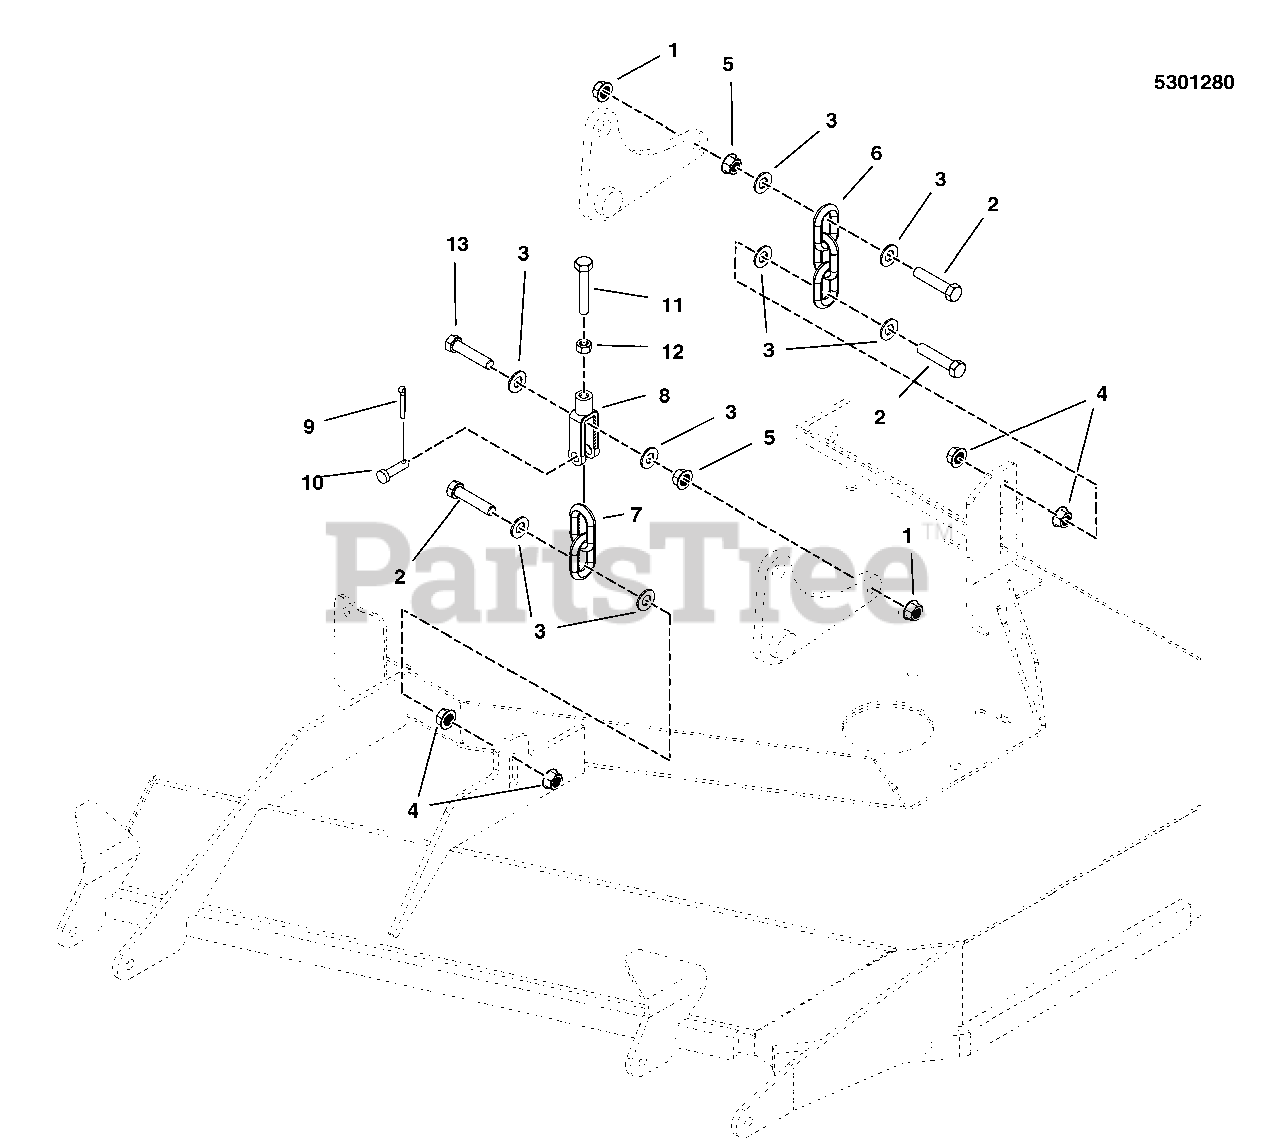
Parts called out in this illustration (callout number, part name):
1	NUT, 3/8-16 HEX NYLOCK FLANGE
2	BOLT, 3/8-16 X 1-3/4" GD5 CZ
3	WASHER, 3/8 SAE
4	NUT, 3/8-16 HEX SERRATED FLANGE
5	NUT, 3/8-16 HEX JAM
6	CHAIN, 5/16 GD30, 3 LINKS
7	CHAIN, 5/16 GD30, 2 LINKS
8	CLEVIS, 5/16-18, 3/8 PIN HOLE, CLR ZINC
9	PIN, 3/32 X .750, COT, ZINC/CLEAR
10	PIN, CLEVIS, 3/8 X 1-1/8, CZ
11	BOLT, 5/16-18 X 2 GD5 TFL
12	NUT, 5/16-18 HEX JAM
13	BOLT, 3/8-16 X 2, GD5, CZ
